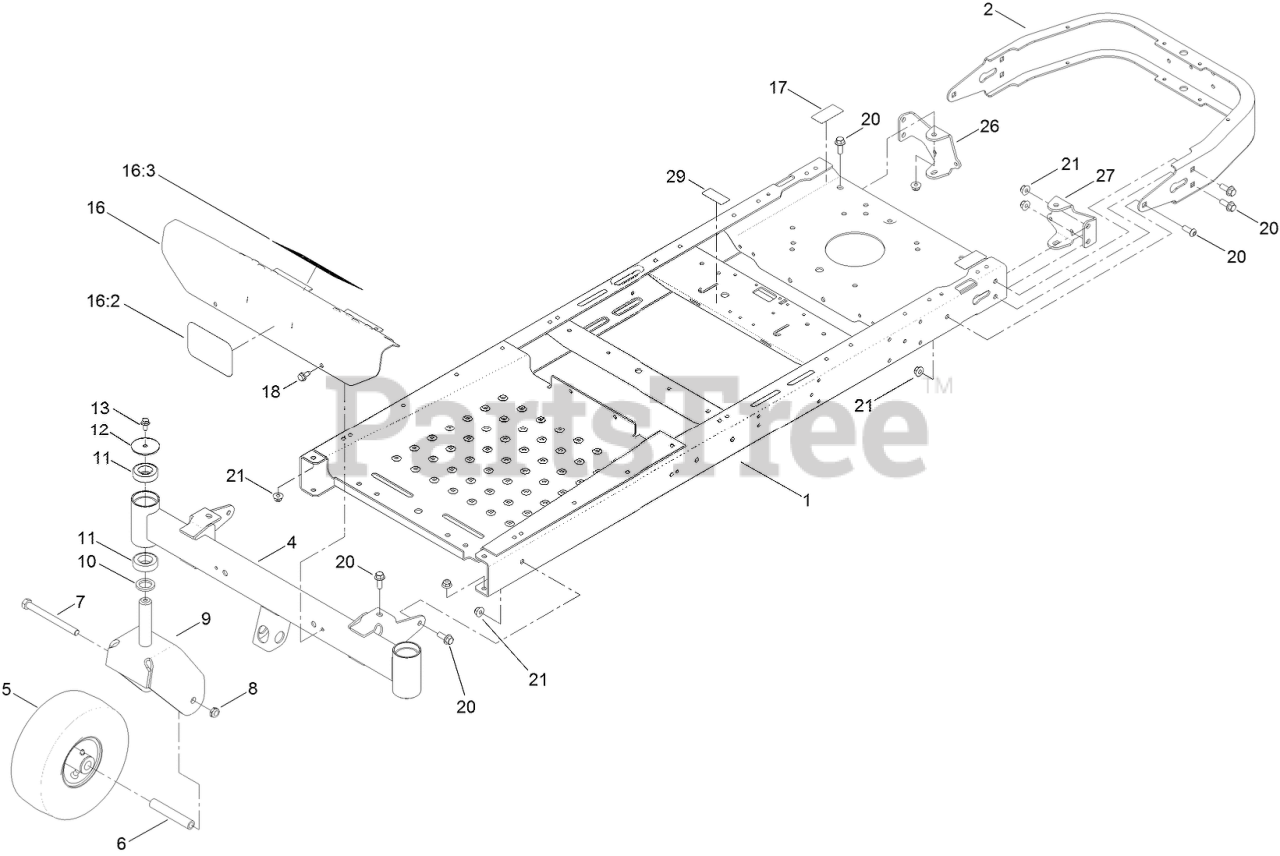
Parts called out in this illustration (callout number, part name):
2	BUMPER-REAR
4	AXLE-FRONT
5	CASTER WHEEL ASM (Cst)
6	BUSHING-SPANNER
7	SCREW-HH
8	NUT-LOCK, NI
9	FORK-CASTER
10	WASHER-THRUST
11	BEARING-BALL
12	WASHER
13	SCREW-HHF
16	FOOTREST ASM
16:3	DECAL-DANGER
17	DECAL-BYPASS
18	SCREW-HWHTF
20	SCREW-HHF
21	NUT-HF, NI
26	MOUNT-HYDRO, REAR (RH)
27	MOUNT-HYDRO, REAR (LH)
29	DECAL-LOCATION, SERVICE DEALER
